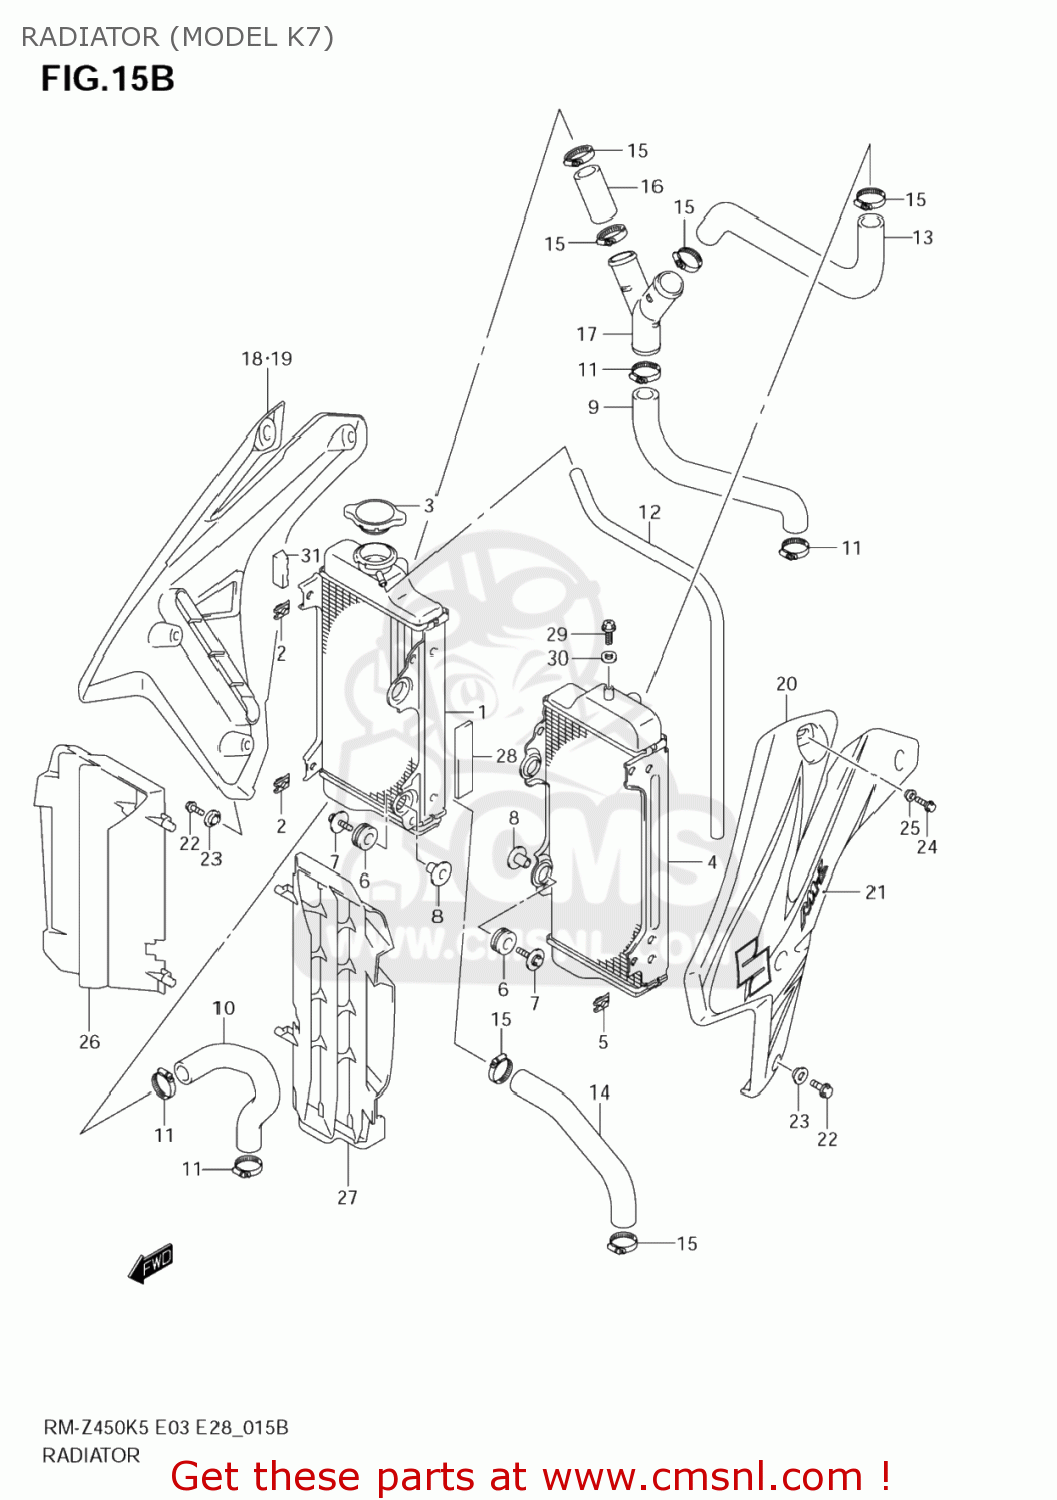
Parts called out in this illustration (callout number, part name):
1	RADIATOR,WATER,R
2	NUT
3	CAP COMP,RADIATOR
4	RADIATOR,WATER,L
5	NUT
6	CUSHION,RADIATOR LWR
7	BOLT(6X25)
8	SPACER(6.5X10.5X14.1)
9	HOSE,RADIATOR INLET
10	HOSE,RADIATOR OUTLET
11	CLAMP
12	HOSE(5X8X2000)
13	HOSE,RADIATOR JOINT UPR NO.1
14	HOSE,RADIATOR JOINT LWR
15	CLAMP
16	HOSE,RADIATOR JOINT UPR NO.2
17	JOINT,RADIATOR HOSE
18	COVER,RADIATOR,R(YELLOW)
19	TAPE,RADIATOR COVER,R
20	COVER,RADIATOR,L(YELLOW)
21	TAPE,RADIATOR COVER,L
22	BOLT(6X12)
23	WASHER,RR BRAK
24	BOLT(6X16)
25	SPACER(6.3X10X6)
26	LOUVER,RADIATOR,R
27	LOUVER,RADIATOR,L
28	CUSHION,RADIATOR
29	UNION BOLT,AIR VENT
30	GASKET(6.4X11.5X0.8) (NAS)
31	CUSHION,RADIATOR COVER,R
